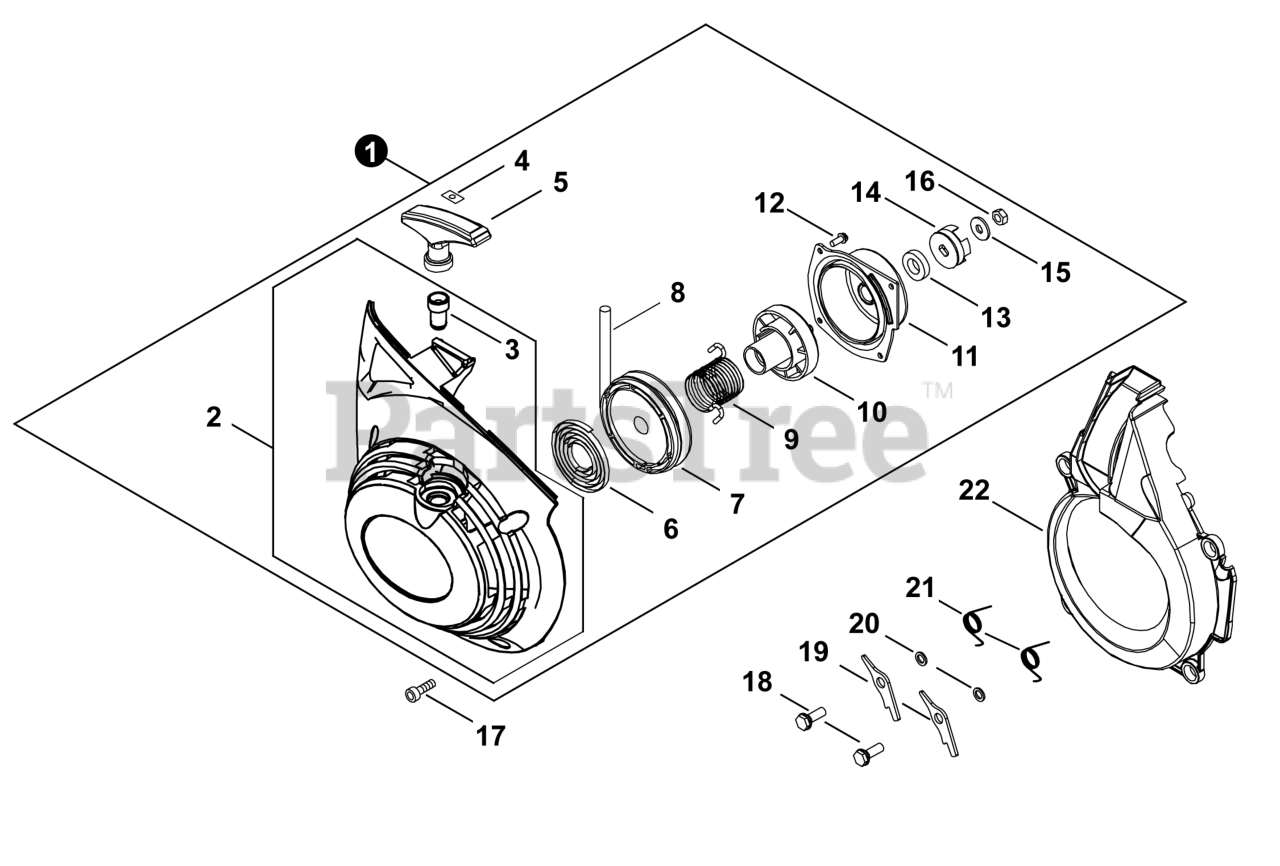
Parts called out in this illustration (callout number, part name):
1	STARTER ASSY
2	CASE ASSY, STARTER
3	GUIDE, ROPE
4	RETAINER, ROPE
5	GRIP, STARTER
6	SPRING, SPIRAL
7	REEL, ROPE
8	ROPE, STARTER
9	SPRING, TORSION
10	SHAFT, STARTER
12	SCREW
13	SEAL, OIL
14	CATCHER, PAWL
16	NUT, HEX M6
19	RATCHET
21	SPRING, COIL
22	COVER, FAN
